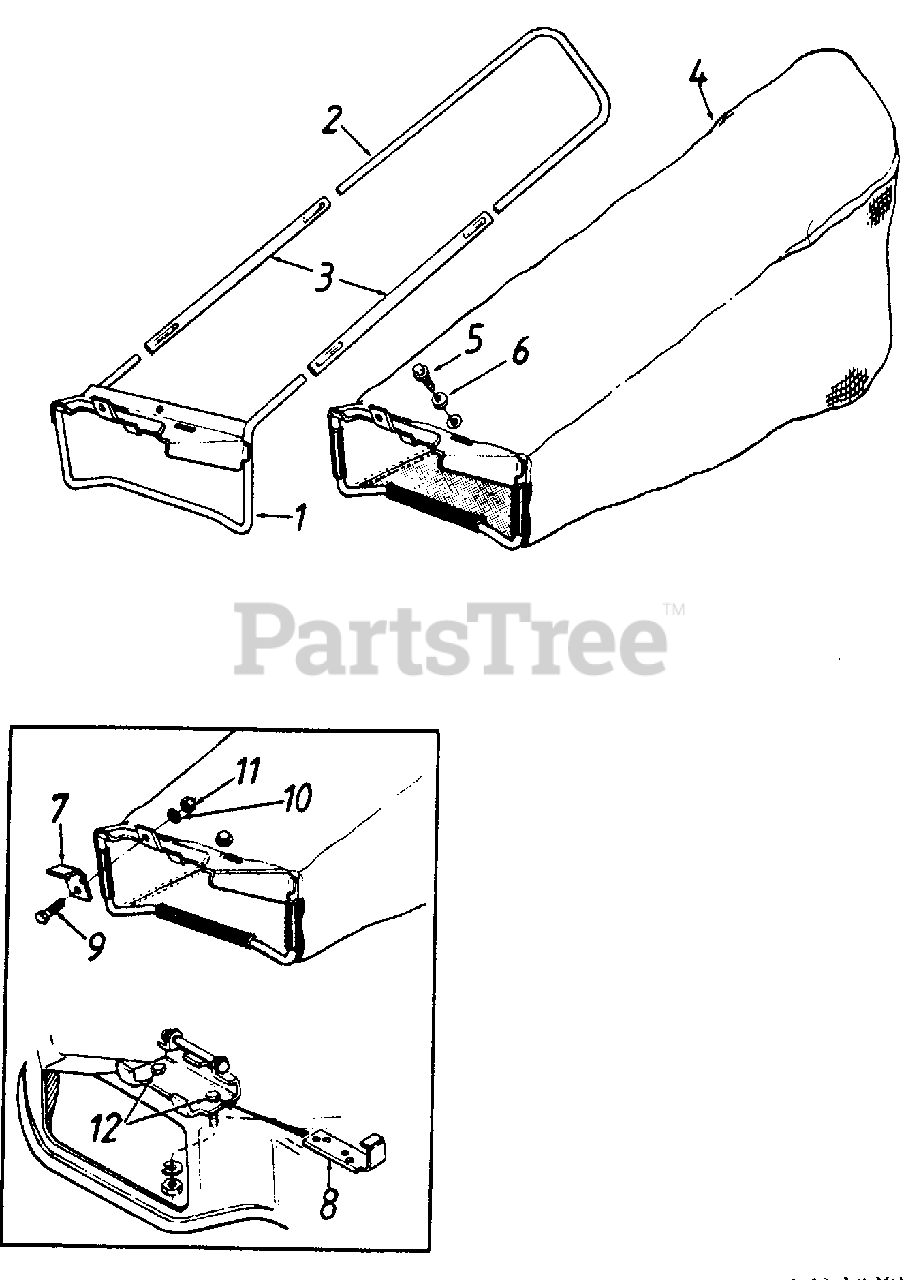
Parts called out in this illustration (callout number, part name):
1	Frame-Lower Ass'y.
2	Frame-Upper
3	Tube Support
4	Grass Bag
5	Hex Wash Hd. TT-Tap Scr. 1/4-20 x 5" Lg.
6	Bell-Wash. 1/4" I.D.
7	Deflector Stop
8	Support Plate
9	Hex Bolt 1/4-20 x .5" Lg.
10	L-Wash. 1/4" I.D.
11	Hex Nut 1/4-20 Thd.
12	Hex Bolt 1/4-20 x .62" Lg.
